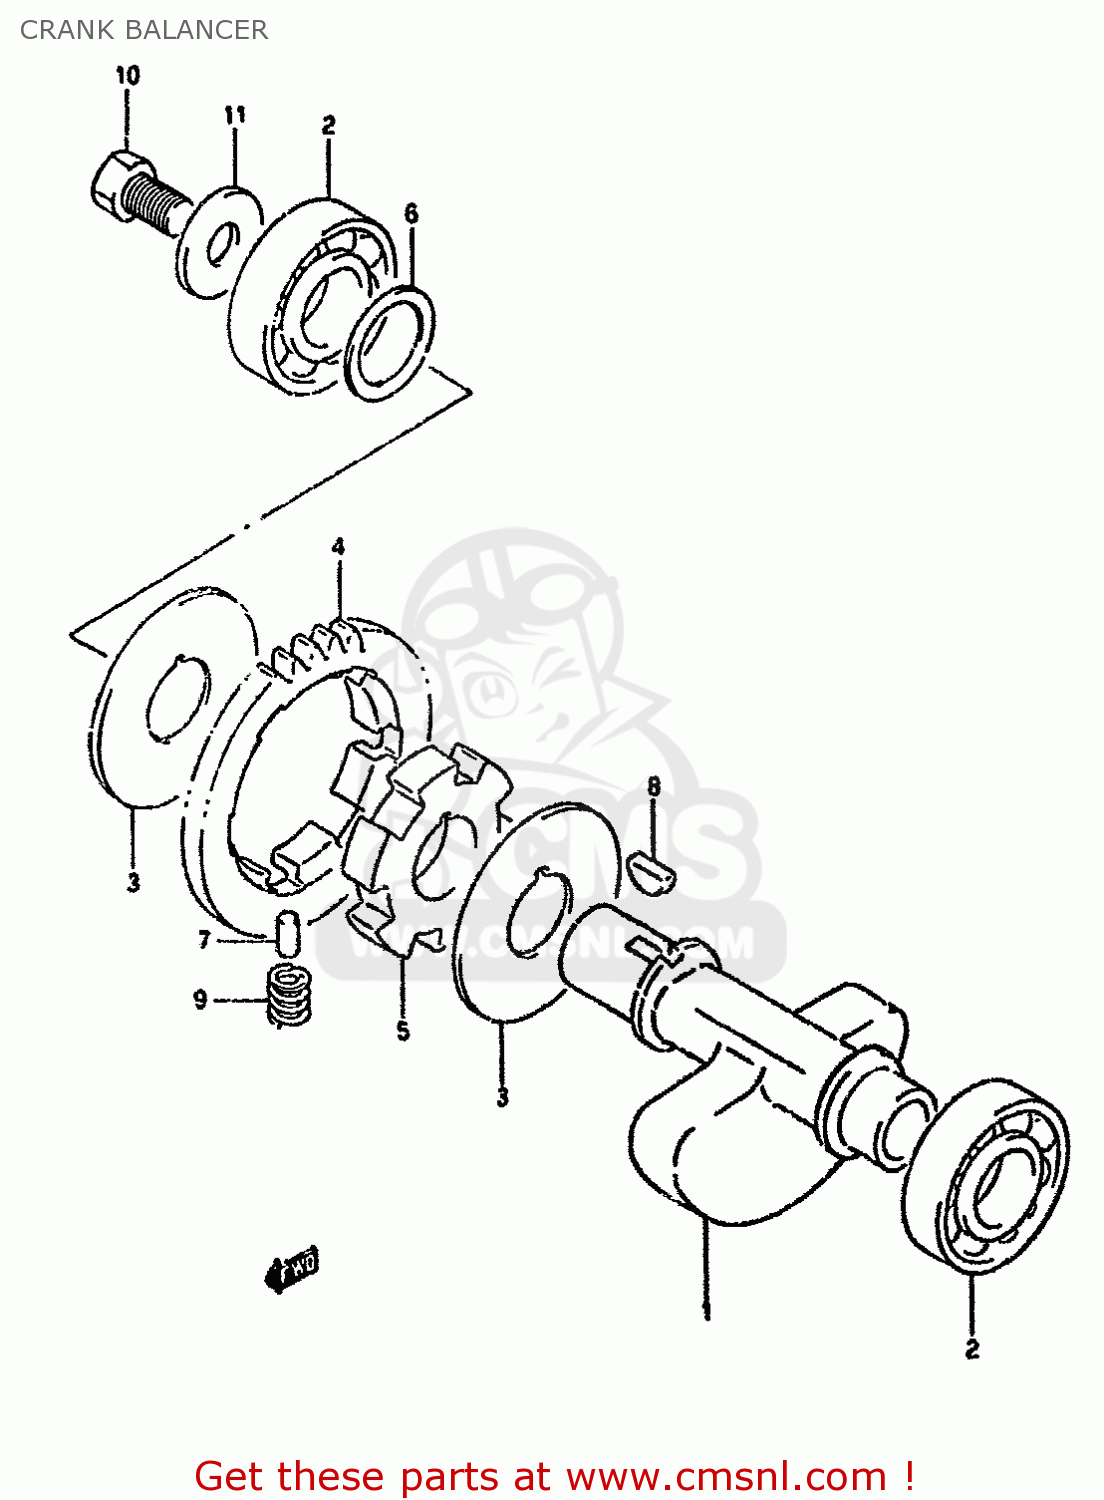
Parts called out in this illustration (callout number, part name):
1	BALANCER,CRANKSHAFT
2	BEARING(20X47X14)
3	WASHER
4	GEAR,CRANK BALANCER
5	RACE,CRANK BALANCER DRIVEN GEAR
6	THRUST WASHER
7	PIN
8	KEY 4MM
9	SPRING
10	BOLT
11	WASHER(10X28X2.2)
